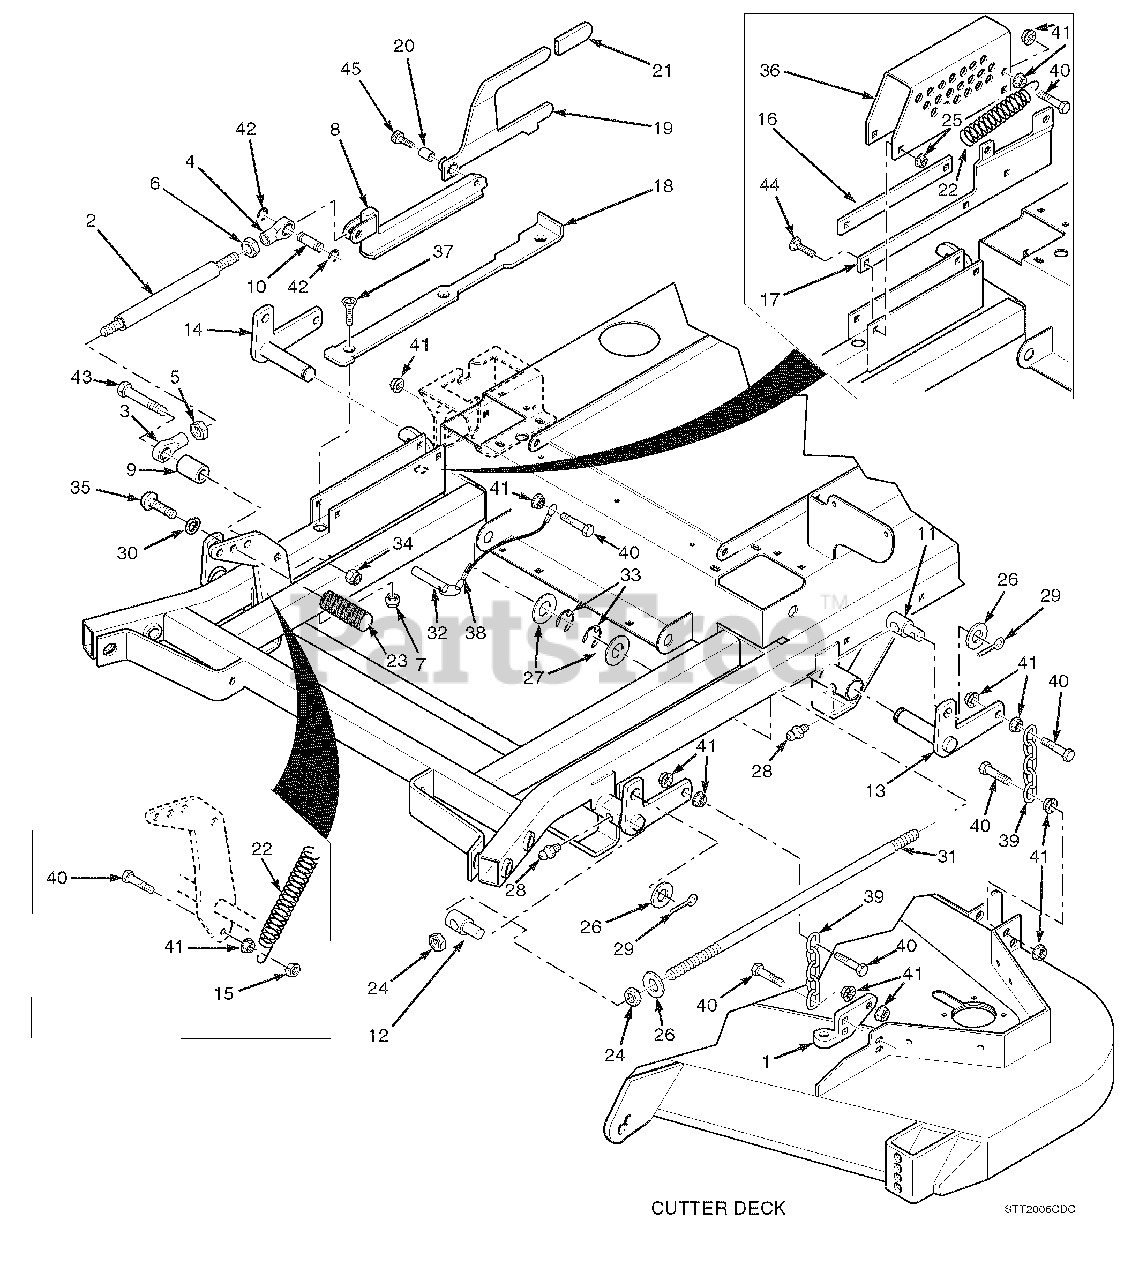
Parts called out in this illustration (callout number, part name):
1	Lever Assembly, Deck Level
2	Link, Deck Lift
3	Rod End, Female - 1/2-20 RH
4	Rod End, Female - 1/2-20 LH
5	Nut, Jam 1/2-20 RH
6	Nut, Jam 1/2-20 LH
7	Nut, 3/8-16 Elastic Stop
8	Slide Weldment, Height Adjustment
9	Spacer, Decklift Pedal
10	Pin, Decklift
11	Swivel Joint, LH
12	Swivel Joint, RH
13	Bellcrank Weldment, LH Rear
14	Bellcrank Weldment, RH Rear
15	Locknut, 3/8-16 Center Lock
16	Guide, Short
17	Guide, Long
18	Lockplate, Decklift
19	Deck Latch
20	Bushing, .502 ID.
21	Grip, Deck Latch
22	Spring, Helper
23	Foot Pedal, Height Adjustment
24	Nut, Hex 5/8-11
25	Nut, Hex Serrated Flange 5/16-18
26	Flatwasher, 5/8"
27	Flatwasher, 1"
28	Grease Fitting
29	Cotter Pin, 3/16 x 1”
30	Lockwasher, 5/8”
31	Stud, 5/8-11 x 22.0"
32	Ring Pin, 1/2 x 3.06"
33	Ring, Retaining 1" External "E"
34	Nut, Hex Elastic Stop 1/2-13
35	Capscrew, 5/8-11 x 1-1/2”
36	Bracket, Cutting Height Adjustment
37	Screw, Cap 5/16-18 x 3" FHHS
38	Lanyard, Deck Height Pin
39	Chain
40	Bolt, Hex Head 3/8-16 x 1-1/2"
41	Nut, Hex Serrated Flange 3/8-16
42	Ring, Retaining 1/2" External "E"
43	Bolt, Hex Head 1/2-13 x 3"
44	Bolt, Carriage 5/16-18 x 1"
45	Bolt, Shoulder 1/2 x 3/4"
